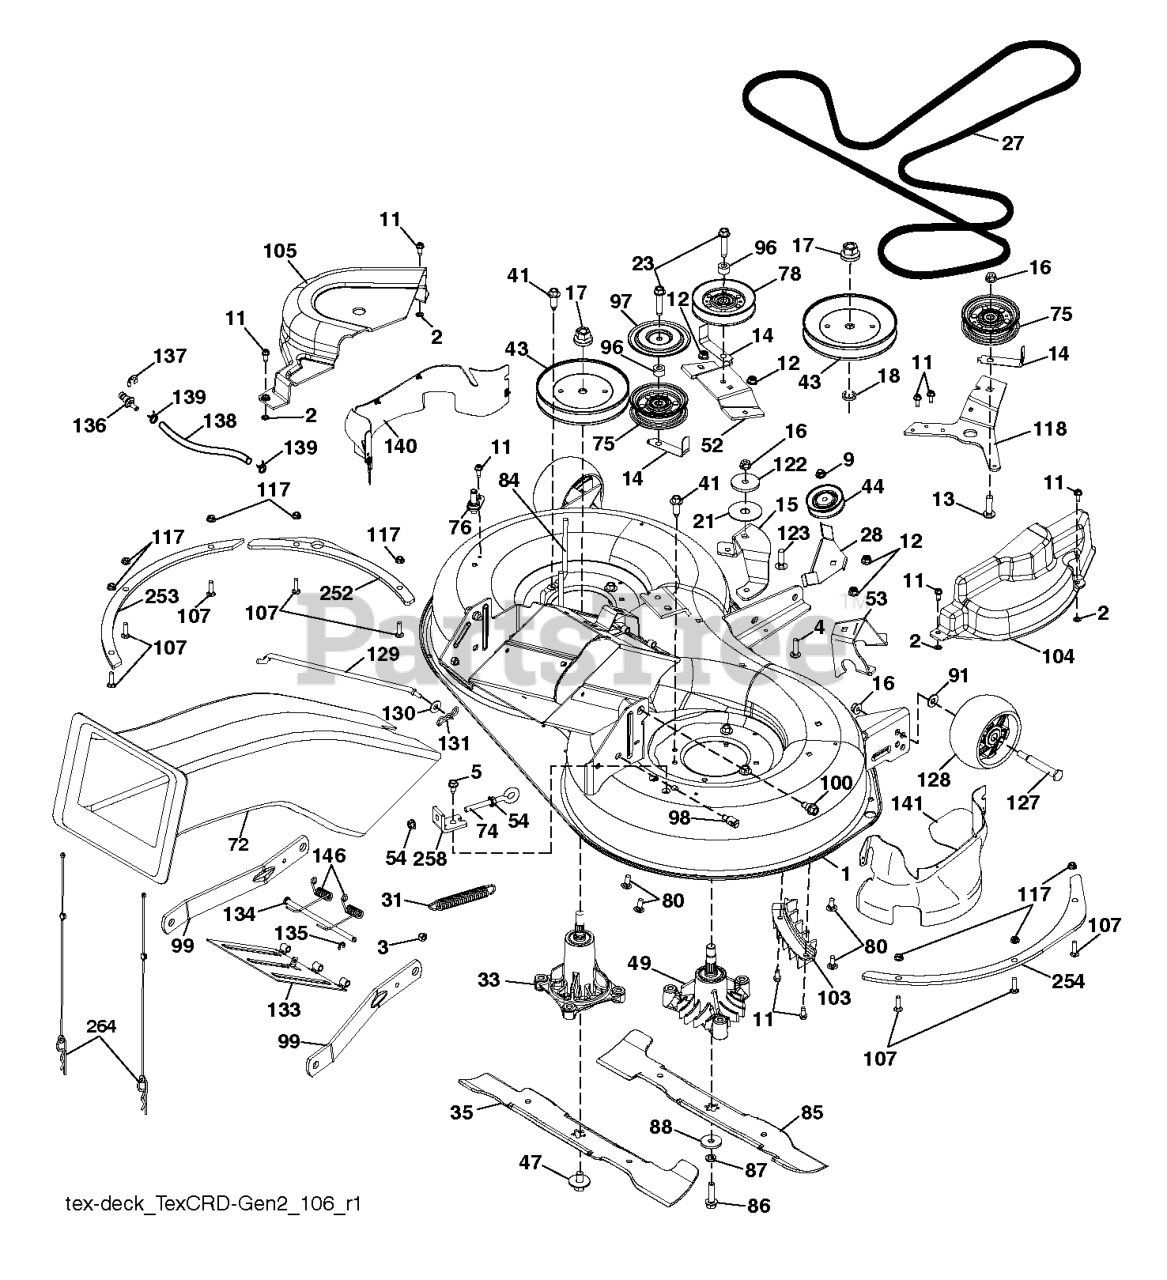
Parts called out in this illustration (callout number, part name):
1	Service Kit
2	PALNUT 1/4
3	GSPW Nuts
4	BOLT.CARRIAGE.5/16-18
5	BOLT.5/16HEX.WHS.HD
9	NUT HEX FLG NYLOCK BLK 5_16-1
11	SCREW.1/4-20X5/8
12	NUT HEXAGON FLANGE 5/16-18 ST
13	GSPW Bolts
14	KEEPER, BELT IDLER
15	BRACKET CRD IDLER ARM MOUNT BL
16	NUT LOCK FLG 3/8-16 UNC
18	WASHER.SPACER.MANDREL
23	BOLT;HEX_3/8-16 X 1.78.CLRZINC
28	KEEPER 97 CRD ANGLED IDLER KEE
31	SPRING.EXTN.42.FCS.TR.DECK.DRV
33	KIT.MANDREL.NONGREASE.TALL
35	BLADE.3N1.LH.CRD.97
41	BOLT.HEX.WASHR.HED.313-18X1.19
43	PULLEY.MANDREL.5.0.PD.38"
44	PULLEY.V-IDLER.
47	SCREW.SEMS.7/16-20X1.HEX.HEAD
49	MANDREL ASM.CRD RH 6PT STAR
52	BRACKET 97 CRD CENTER V-IDLER
53	BRACKET 97 CRD ANGLED V-IDLER
54	GSPW Hardware
72	CHUTE.SLOTTED.HOLES.TEX.CRD.II
74	GSPW Bolts
76	1/2" BARB.DECK.WASHOUT.PORT
78	REPL BY 532 1467-63
80	GSPW Bolts
84	BELT KEEPER.MANDREL.38"COATED
85	BLADE.3N1.RH.CRD.97
86	BOLT.3/8-24X1.25GR8. LHTHRD
88	WASHER.BLADE
96	SPACER
97	PROTECTOR
98	STUD.W/"D"ANTI-ROTATION
99	ARM.SUSPENSION.MOWER.R
100	BOLT.SHOULDER
103	GUARD GUARD FRONT VENT
104	GUARD 97CRD RH MANDREL COVER;
105	MANDREL MANDREL COVER LH
107	BOLT CUP HEAD SQUARE NECK 1/4-
117	NUT T
118	ARM 97 CRD IDLER ARM BLACK E-C
122	SPACER.RETAINER.MOWER
128	WHEEL.GAUGE.RALLY
129	ROD ROD. SWAY CRD GEN II
131	PIN.COTTER.5/16.BOW TI
133	DOOR
135	E-RING.5/16"
136	PLUG WASHOUT PORT HOOKUP
138	HOSE.3/8ID.BULK.12"
140	GUARD.ASSEMBLY.97.LH.FRENCH
141	GUARD.ASSEMBLY.97.RH.FRENCH
146	SPRING SPRING: EZ MULCH DOOR
252	PLATE.REINFORCEMENT.X431
253	PLATE.REINFORCEMENT.LHS.X431
254	PLATE.REINFORCEMENT.LHS.X431
258	BRACKET CRD ELEC DECK DRIVE TE
